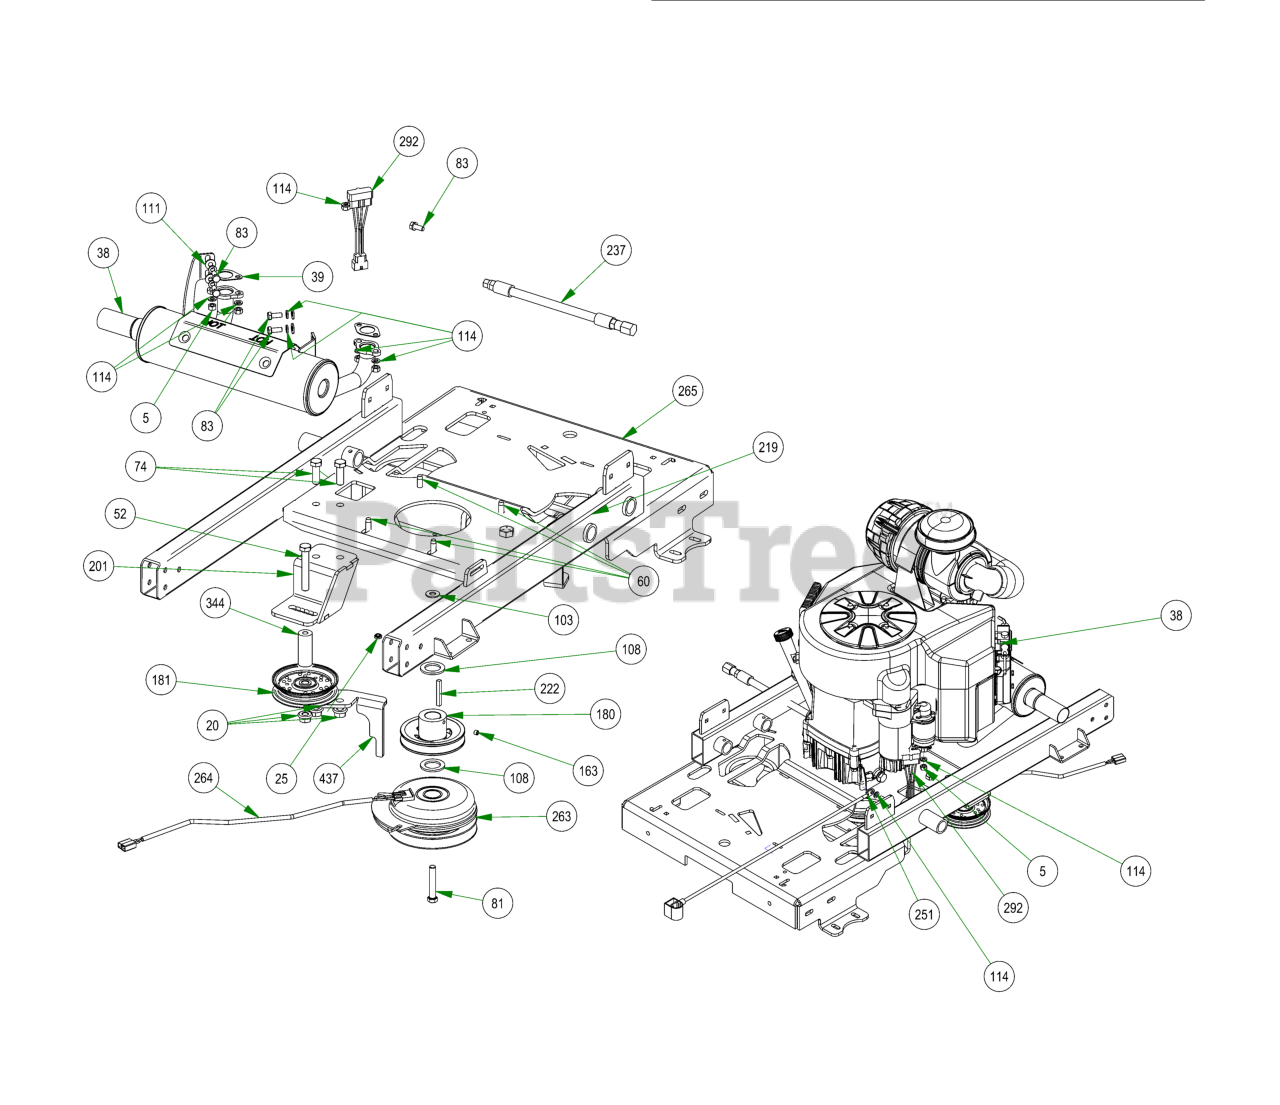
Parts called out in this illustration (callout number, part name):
5	M8-1.25 DIN 934 HEX NUT (CL.8) ZINC
20	1/2-13 NYLON INSERT FLANGE LOCKNUT ZINC
25	5/16-18 NYLON INSERT JAM LOCKNUT ZINC
38	Revolt Kawasaki FX850 Exhaust
39	Exhaust Gasket
52	1/2-13 X 3-1/4 HEX CAP SCREW (GR.5) ZINC
60	3/8-16 X 1-1/8 HEX WASHER UNSLOT SERRATED (TRI-LOB) TRS ZINC YELLOW
74	1/2-13 X 1-1/2 HEX CAP SCREW (GR.5) ZINC
81	7/16-20 X 2-1/2 HEX CAP SCREW (GR.8) ZINC YELLOW
83	M8-1.25 X 20MM DIN 933 HEX TAP BOLT (CL 8.8) ZINC
103	3/8 FLAT WASHER USS (1" OD) ZINC
108	1.140 ID X 1.750 OD X .132 THICK FLAT WASHER PLAIN
111	1/4 USS FLAT WASHER (3/4 OD) ZINC
114	5/16 SPLIT LOCKWASHER ZINC
163	5/16-24 X 1/4 SOCKET SET SCREW (CUP PT) PLAIN
180	4 3/4 Motor Pulley
181	4 3/4 Idler Pulley - ABFI-76
201	Idler Pulley Bracket Weldment 2019 Stand On
219	2019 Stand On Pump Belt (Timken# 47-2827)
222	1/4 X 2 SQ MACHINERY KEY 1018 STL PLAIN
237	Kawasaki Oil Drain
251	24 inch Black Cable – MZ/ZT
263	Clutch Assembly
264	Clutch Pigtail
265	2019 Stand On Frame
292	2019 Harness Adaptor-Gen2 FX-ALL
344	Stand On Spacer 2.5''
433	Kawasaki Engine FX-850-V-CS09R
437	2019 Stand On Clutch Stop Bracket
